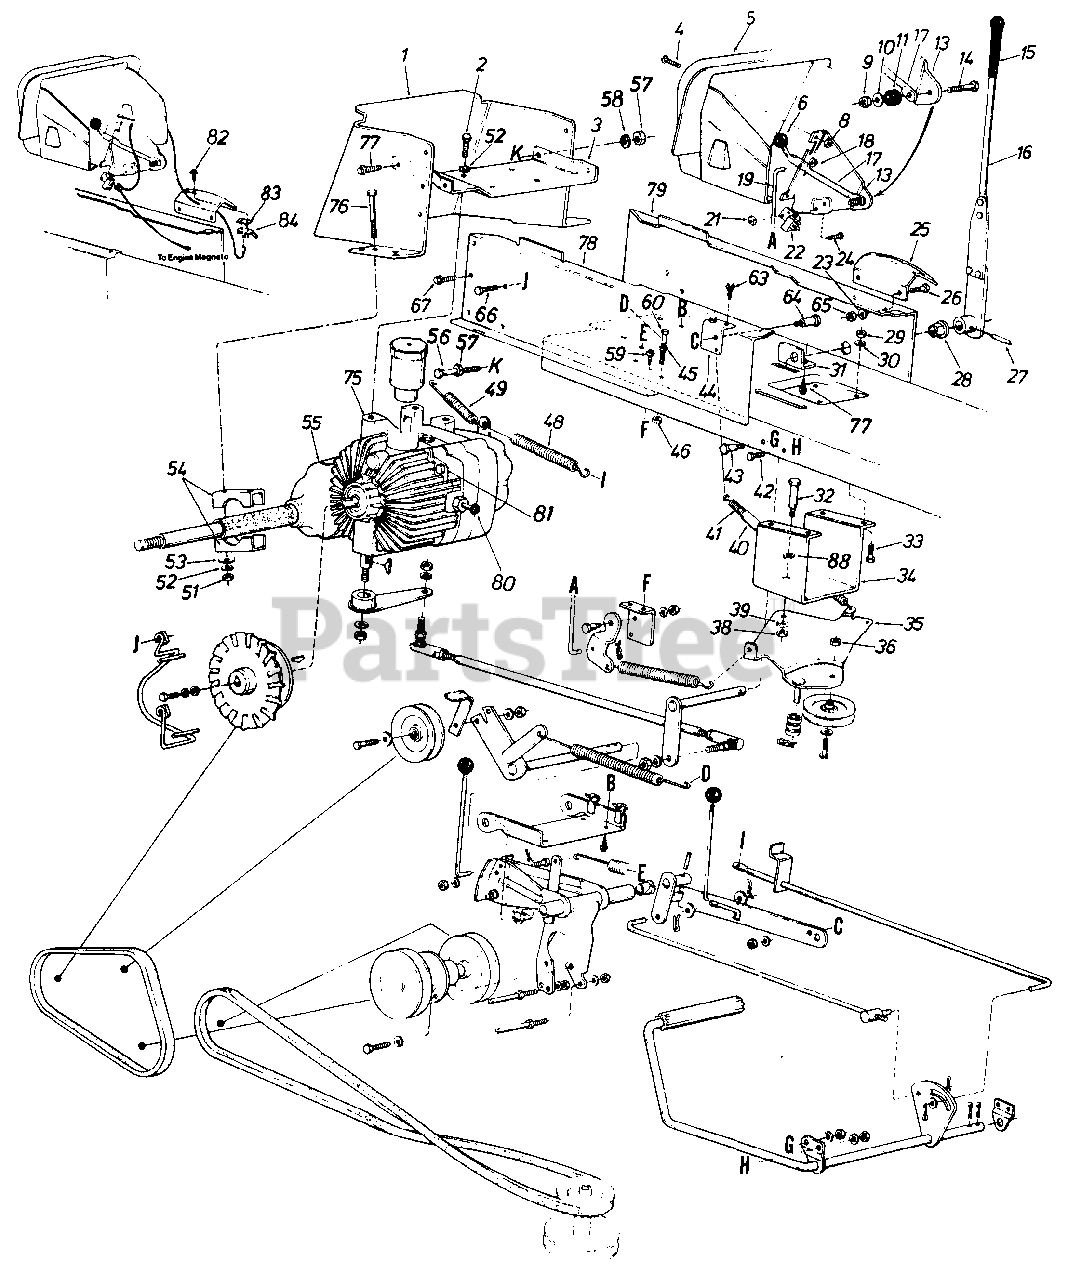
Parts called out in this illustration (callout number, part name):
1	Hitch Plate
2	Hex Bolt 3/8-16 x .75" Lg.
3	Rear Axle Support Brkt.
4	Truss Mach. Scr. 1/4-20 X .50" Lg.
5	Dash Panel Ass'y.
6	Knob Blade Clutch
8	Hex Sems Nut 1/4-20 Thd.
9	Hex Cent. L-Nut 1/4-20 Thd.
10	IFl-Wash. .28" I.D. x .74" O.D. x .063
11	Rubber Wash. .33" I.D. x .871' O.D x .30
13	Deck Clutch Cont. Brkt.
14	Hex Bolt 1/4-20 x 1.25" Lg.
16	Control Arm Ass'y.
17	Blade Clutch Lever
18	Push Nut 1/4" O.D. Rod
19	Deck Control Rod
21	Hex Nut #10-24 Thd.
22	Safety Switch
23	L-Wash. 5/16" I.D.
24	Truss Mach. Scr. #10-24 x .50" Lg.
25	Speed Control Bracket
26	Hex Bolt 5/16-18 x .62" Lg.
27	Spring Pin Spiral 1/4" Dia. x 1.5" Lg.
28	Hex Flange Brg.
29	Hex Nut 5/16-18 Thd.
30	L-Wash. 5/16" I.D.
31	Speed Control Shaft Brkt.
32	Shld. Scr. .437" Dia. x .162" Lg.
33	Hex Bolt 5/16-18 x 1.00" Lg.
34	Idler Support Brkt.
35	Idler Brkt. Ass'y.
36	Hex L-Nut 3/8-16 Thd.
38	Hex Nut 5/16-18 Thd.
39	L-Wash. 5/16" I.D.
40	Ccnvoluted Conduit .50" I.D.
41	Ext. Spring .50" O.D. x 6.37" Lg.
42	Hex Bolt 3/8-16 x .62" Lg.
43	Shld. Scr. .50" Dia. x .395" Lg.
44	Parking Brake Cam Mtg. Brkt.
45	Hex Nut 5/16-28 Thd.
46	Hex L-Nut 5/16-18 Thd.
48	Brake Tension Spring
49	Ext. Spring Brake Return
51	Hex Nut 3/8-16 Thd.
52	L-Wash. 3/8" I.D.
53	Fl-Wash. .390" I.D. x 1.00" O.D. x .125" Thk.
54	Rear Axle Bracket
55	Transaxle
56	Hex Bolt 1/4-20 x 2" Lg.
57	Hex Nut 1/4-20 Thd.
58	L-Wash. 1/4" I.D.
59	Hex Wash. Hd. Self-Tap Scr. 1/4-20 x .50" Lg.
60	Hex Bolt 5/16-18 x 1.50" Lg.
63	Hex Wash. Hd. Self-Tap Scr. 1/4-20 x .50" Lg.
64	Shld. Scr. .437" Dia. x .162" Lg.
65	Hex Nut 5/16-18 Thd.
66	Hex Wash. Hd. Scr. 3/8-16 x .50" Lg.
67	Hex Wash. Hd. Self-Tap Scr. 5/16-18 x .75" Lg.
75	Hydrostatic Pump Comp.
76	Hex Bolt 3/8-16 x 3.5" Lg.
77	Hex AB-Tap Scr. 5/16 x .75" Lg.
78	Side Panel Upper Frame R.H.
79	Side Panel Upper Frame L.H.
81	Socket Hd. Bolt 3/8-16 x 2.75 Lg.
82	Hex Wash. Hd. Scr. #8 x .50" Lg.
83	Insulator Nut Plate
84	Spring Switch
88	Wave Washer
